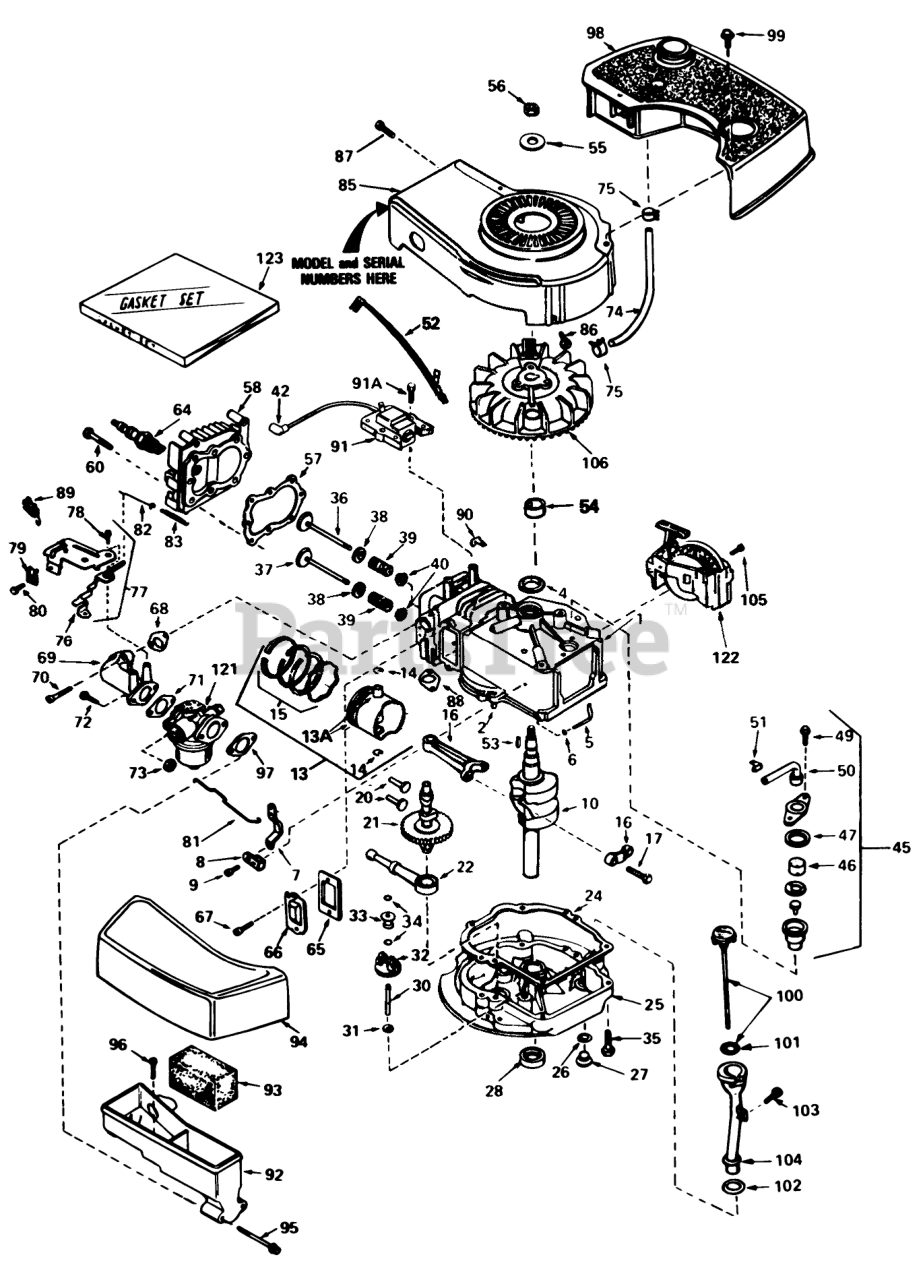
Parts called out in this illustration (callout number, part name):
1	Cylinder Assy. (Incl. #2 & 4)
2	Pin-Dowel
4	Seal-Oil
5	Rod, Governor (Incl. #6)
6	Washer-Flat
7	Governor Lever
8	Clamp-Lever, Governor
9	Screw
10	Crankshaft
13	Piston, Pin & Ring Assy. (Std.)(Incl. #13A, 14 & 15)
13	Piston, Pin & Ring Assy. (.010 oversize)(Incl. #13A, 14 8 15)
13	Piston, Pin & Ring Assy. (.020 oversize)(Incl. #13A, 14 8 15)
13A	Piston & Pin Assy. (Std.)(Incl. #14)
13A	Piston & Pin Assy. (.010 oversize)(Incl. #14)
13A	Piston & Pin Assy. (.020 oversize)(Incl. #14)
14	Ring-Retaining, Piston Pin
15	Ring Set (Std.)
15	Ring Set (.020" OS)
15	Ring Set (.010" OS)
16	Rod Assy., Connecting (Incl. #17)
17	Bolt-Rod, Connecting
20	Lifter-Valve
21	Camshaft(Mech.Comp. Release)
22	Oil Pump ASM
24	Gasket, Mounting
25	Flange Assy., Mounting (Incl. #26 thru 30)
26	Gasket-Oil Drain
27	Plug Oil Drain
28	Seal Oil
30	Shaft-Governor
31	Washer-Flat
32	Gear Assy., Governor (Incl. #31)
33	Spool-Governor
34	Ring-Retaining
35	Screw (1/4-20 x 1-1/4)
36	Valve, Intake (Std.)(Incl. #40)
36	Valve, Intake (1/32" oversize)(Incl. #40)
37	Valve, Exhaust (Std.)(Incl. #40)
37	Valve, Exhaust (1/32" oversize)(Incl. #40)
38	Cap-Upper Valve Spring
39	Spring-Valve
40	Cap-Valve, Spring
42	Cover-Spark Plug
45	Breather Assy. (Incl. #46 thru 51)
46	Element-Breather
47	Gasket-Breather
49	Screw (10-24 x 9/16)
50	Tube, Breaker
51	Clip, Breather
52	Wire-Ground
53	Key-Flywheel
55	Washer-Belleville
56	Nut-Flywheel
57	63573 GIL 42 SNWTHW
58	Head-Cylinder
60	Screw (5/16-18x1-1/2)
64	Plug, Spark (J17LM or equiv.)
64	Plug, Spark (Champion RCJ-8)
65	Gasket-Breather
66	Cover-Valve
68	Gasket-Intake
69	Pipe, Intake (Incl. #68)
70	Screw (1/4-20 x 1)
71	Gasket-Carburetor
72	Screw (1/4-28 x 7/8)
73	Nut and Lock Washer (1/4-28)
74	Line-Fuel
75	Clamp-Line, Fuel
76	Lever Control
77	Control Assy., Speed (Incl. #76, 78 & 89)
78	Screw, Hex Washer Hd Shoulder Self-Tap
79	Conduit
80	Screw (10-32 x 3/8)
81	Link-Throttle
82	Link Governor Spring
83	Spring Governor
85	Housing-Blower
86	Screw (1/4-20x19/32)
87	Screw (10-24 x 9/16)
88	Gasket Exhaust
89	Terminal
90	Clip-Wire
91	Lamination 8 Coil Assy. (Solid State)(Incl. #42)
91A	Screw
92	Body Air Cleaner
93	Filer, Air
94	Cove, Air Cleaner
95	Screw Fil Hd.
96	Screw, Hex Hd.
97	Gasket-Air Cleaner
98	Tank-Fuel
99	Screw (10-32 x 35/64)
100	Dipstick, Oil (Incl. #101)
103	Screw (10-32 x 1/2)
104	Tube-Oil Fill
105	Screw (1/2-20x5/8)
106	Flywheel
121	Carburetor (Incl. #71)
122	Starter-Sidemount
123	Gasket Set
